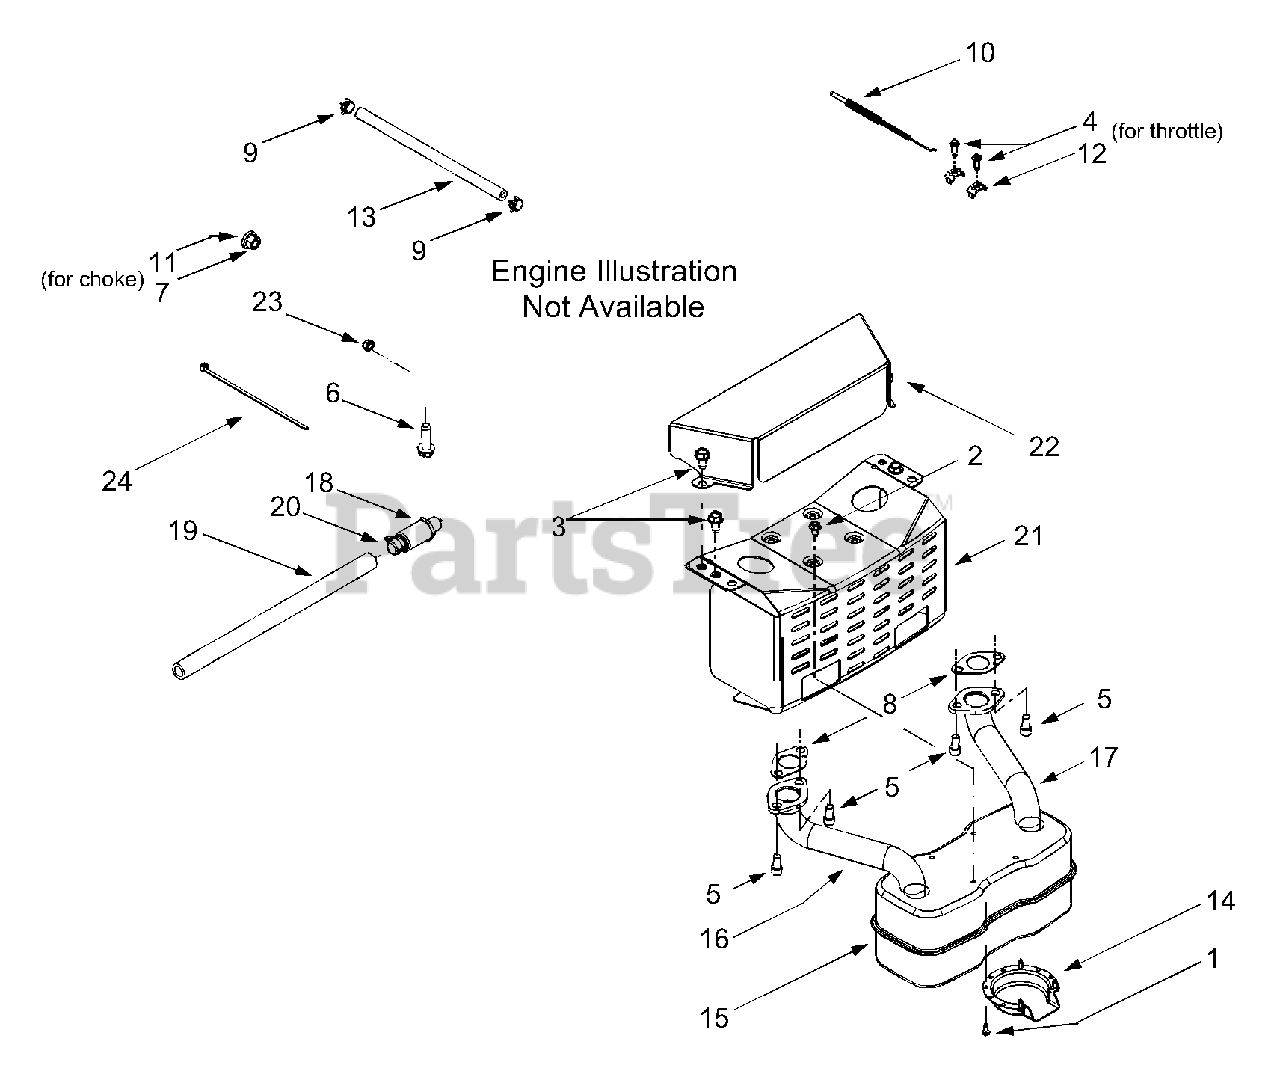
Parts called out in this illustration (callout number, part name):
1	Self-tapping Screw, #8-18 x.50
2	Self-tapping Screw, 1/4-20 x.50
3	Self-tapping Screw, 5/16-18 x.625
4	Screw, #10-32 x.625 (OHV V-Twin)
5	Socket Cap Screw, 5/16-18 x.625
6	Self-tapping Screw, 3/8-16 x 1.25
7	Hex Nut, 3/8-16
8	Exhaust Gasket (OHV V-Twin)
9	Hose Clamp
10	Throttle Cable ( OHV V-Twin)
11	Lock Washer,.406 x.875 x.059
12	Casing Clamp (OHV V-Twin)
13	Fuel Line Hose
14	Muffler Deflector
15	Muffler, Twin Inlet ( OHV V-Twin)
16	RH Exhaust Pipe (OHV V-Twin)
17	LH Exhaust Pipe (OHV V-Twin)
18	Oil Drain Valve
19	Oil Drain Hose
20	Oil Drain Cap
22	Engine Heat Shield (OHV V-Twin)
23	Hex Sems Nut, 1/4-20 (OHV V-Twin)
24	Cable Tie
